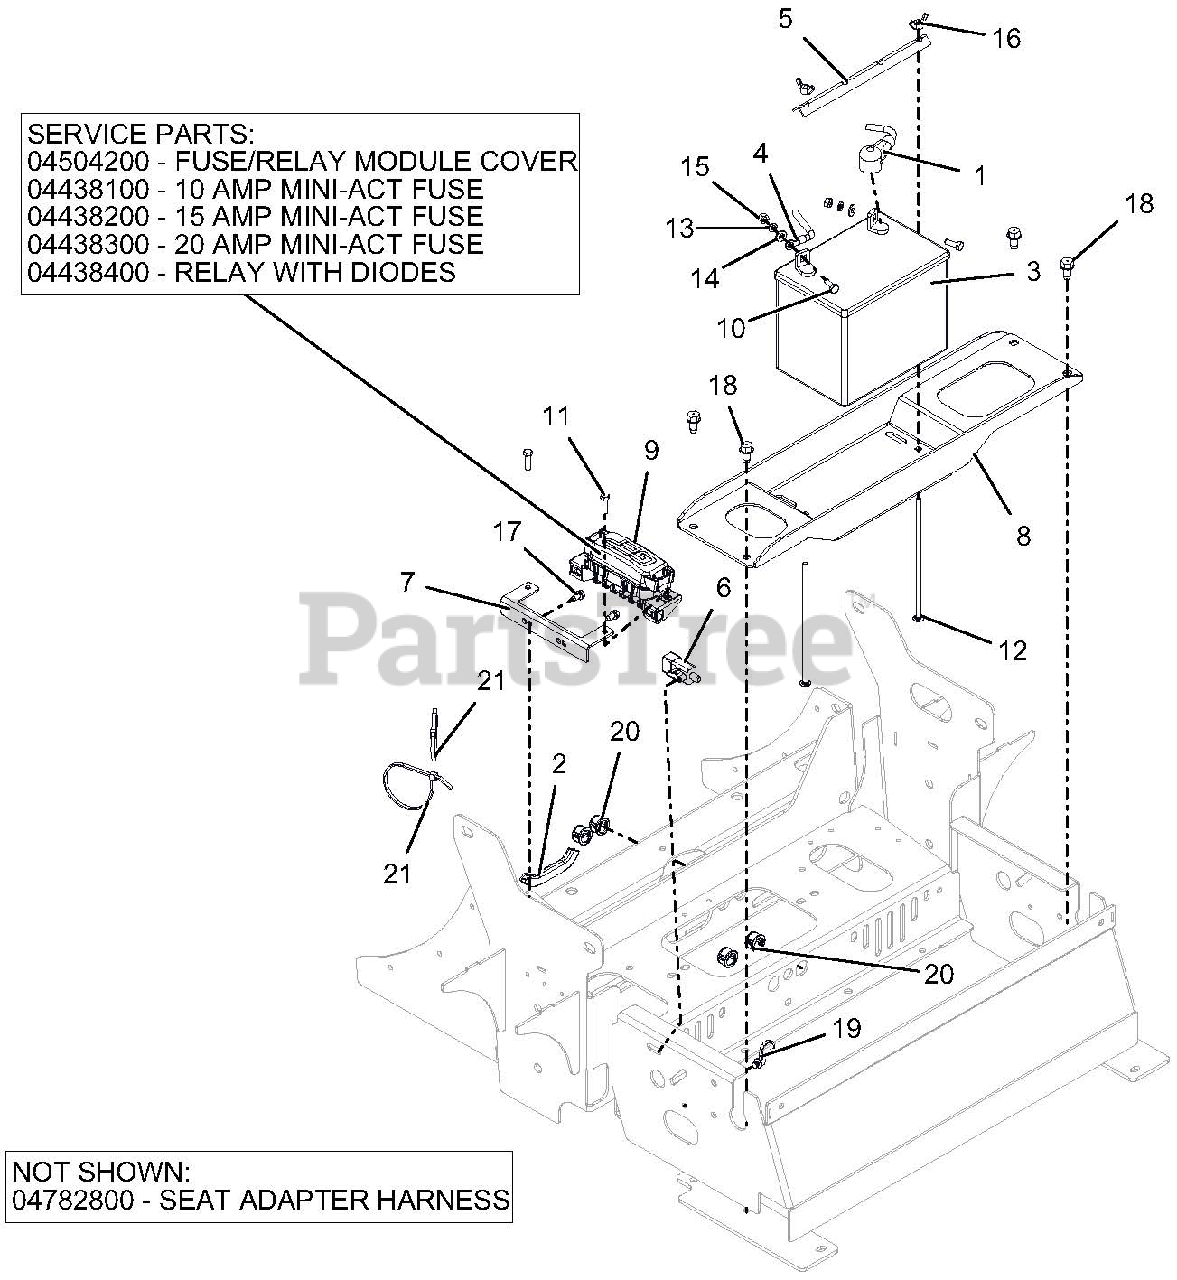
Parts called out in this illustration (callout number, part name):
1	CABLE, POS BATT W/ BOOTS 6 X 35
2	STRIP, COWL - 1.50 LG
3	BATTERY, 300 CCA 10U1L
4	CABLE, NEGATIVE BATTERY 35.00"
5	HOLD DOWN - BLK
6	SWITCH, SNAP IN -N.O./N.O
7	BRKT, FUSE HOLDER MOUNTING-RED
8	TRAY, BATTERY-RED
9	HARNESS, PT400 GAS WIRE
9	FUSE/RELAY MODULE COVER
9	10 AMP MINI-ACT FUSE
9	15 AMP MINI-ACT FUSE
9	20 AMP MINI-ACT FUSE
9	RELAY WITH DIODES
10	BLT-HEX .25-20X.75 GR5 YWZC
11	@BLT-HEX M6-1.0X25 YWZC
12	BLT-RDHDSQNK .25-20X7.50 G2 YWZC
13	WSHR-LK .25X.062 REG YWZC
14	WSHR-FL-STL.281X.62X.065 YWZC
15	NUT-HEX .25-20 YWZC
16	NUT-LOCKING WING 1/4-20
17	SCR-TAP .25-20X.50 HWH TR YWZ
18	SCR-TAP .38-16X.75 HWH TR YWZ
19	CABLE TIE W/ TREE
20	BUSH, PANEL SNAP .687X.875X.56
21	CABLE, TIE 5.50 LG
